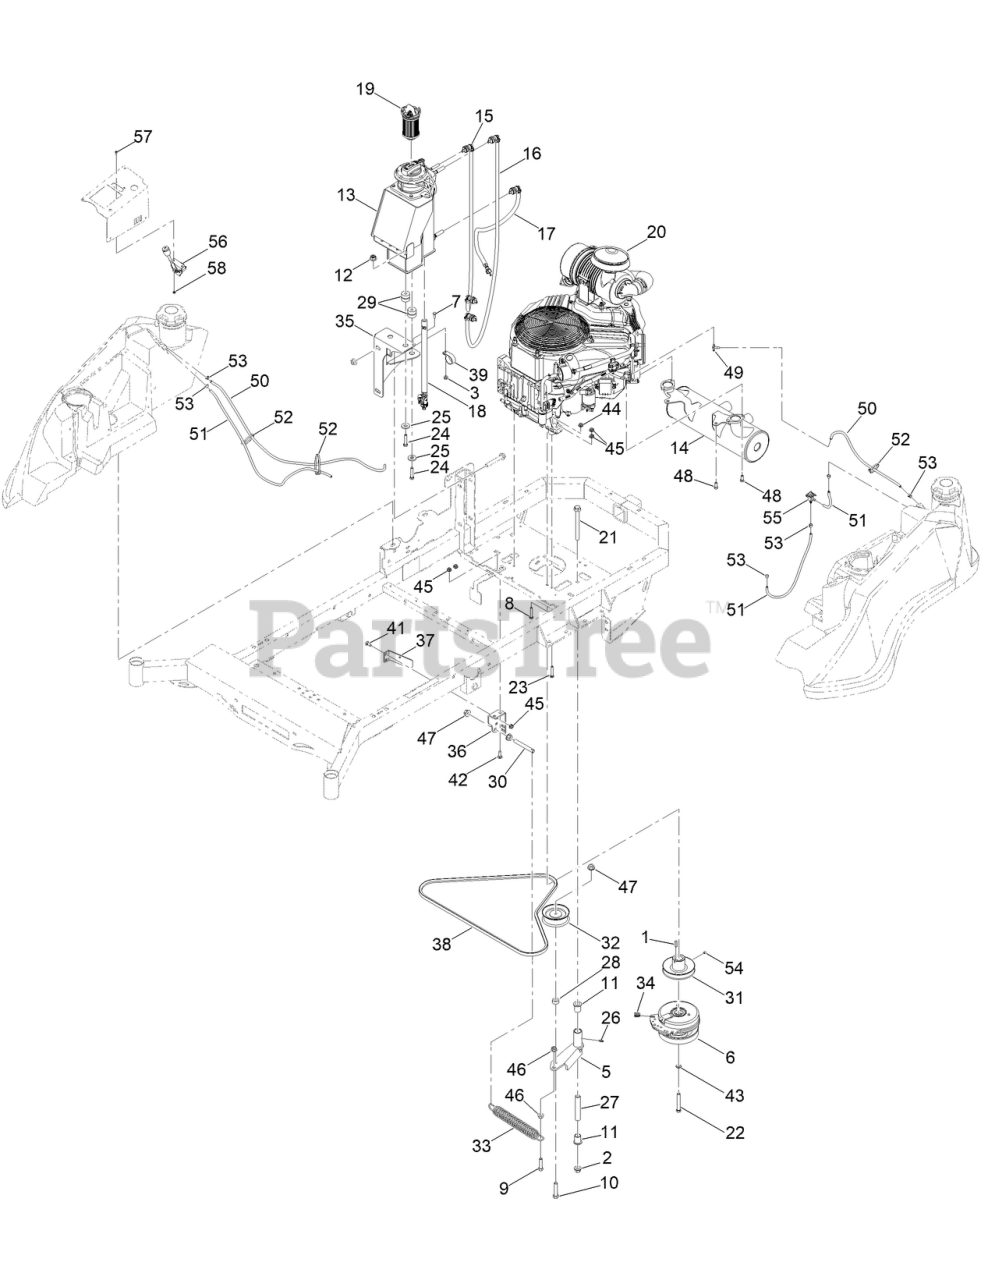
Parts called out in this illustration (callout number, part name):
2	NUT-LOCK
3	NUT-HF
5	4IN PUMP IDLER PULLEY ARM ASSY
6	WARNER PTO CLUTCH
7	SCREW-HH
8	SCREW-HH
9	SCREW-HH
10	SCREW-HH
11	3/4IN ID X15/16IN OD X 1-1/8IN FLNG BUSH
12	3/8-16 NYLON INSERT FLANGE L/NUT YZ
13	VANGUARD OIL GUARD TANK
14	DUAL EXH SYSTEM W/MUFF BIG BLOCK ENGN
15	OIL HOSE ASSY SUPPLY
16	OIL HOSE ASSY SCAVENGE
17	OIL HOSE ASSY VENT
18	OIL FLEX DRAIN HOSE
19	OIL FILTER FOR OIL GUARD
20	VANGUARD 40HP EFI WITH OIL GUARD
21	1/2-13 X 5-1/2 HEX FLANGE BOLT GR 8 ZY
22	7/16-20 X 3 HEX C/S GR 8 ZC YELLOW
23	5/16-18 X 1-3/4 HEX C/S GR 5 ZINC YELLOW
24	3/8-16 X 1-3/4 HEX C/S GR 2 ZINC
25	1/2 FENDER WASHER 1-1/4IN OD ZINC
26	1/4IN DRIVE TYPE GREASE FITTING YZ
27	MWR INNER IDLER SPACER
28	MWR PULLEY SPACER
29	OIL GUARD ISOLATOR
30	MWR PUMP IDLER SPRING TENSIONER
31	MWR HYDRAULIC PUMP DRIVE PULLEY (B-BELT)
32	4IN DIESEL AND ECONOMY MWER IDLER PULLEY
33	MWR DECK SPRING
34	MWR CLUTCH ROTATION STOP BRKT SLEEVE
35	MWR OIL GUARD TANK BRKT BLACK
36	MWR PUMP IDLER TENSIONING BRKT BLACK
37	MWR CLUTCH ANTIROTATION BRKT BLACK
38	MWR PUMP BELT XD B X 69.40IN EFF LNGTH
39	1-1/4IN CUSHIONED LOOP CLAMP BLACK
41	BOLT-CARR
42	5/16-18 X 1-1/4 CARRIAGE BOLT ZC/YEL
43	WASHER-LOCK
44	3/8-16 HEX FLANGE NUT W/SERR ZINC YELLOW
46	NUT-HF
47	NUT-HHF
48	M8-1.25 X 20MM HEX FLANGE BOLT ZINC 10.9
49	STAND-ON FUEL LINE T-CONN (3/16IN X 3IN)
50	MWR FUEL TANK BLACK 3/16IN VENT TUBE 1FT
51	1/4IN SAE J30R7 BULK HOSE 1FT
52	TIE-CABLE
53	1/2IN (#8) HOSE CLAMP
54	5/16-18 X 3/8 SOCKET SET SCREW
55	STAND-ON FUEL SELECTOR/SHUT OFF VALVE
56	KAWASAKI EFI THROTTLE
57	10-24 X 1/2 SOCKET C/S 18-8 SS
58	NUT-LOCK
